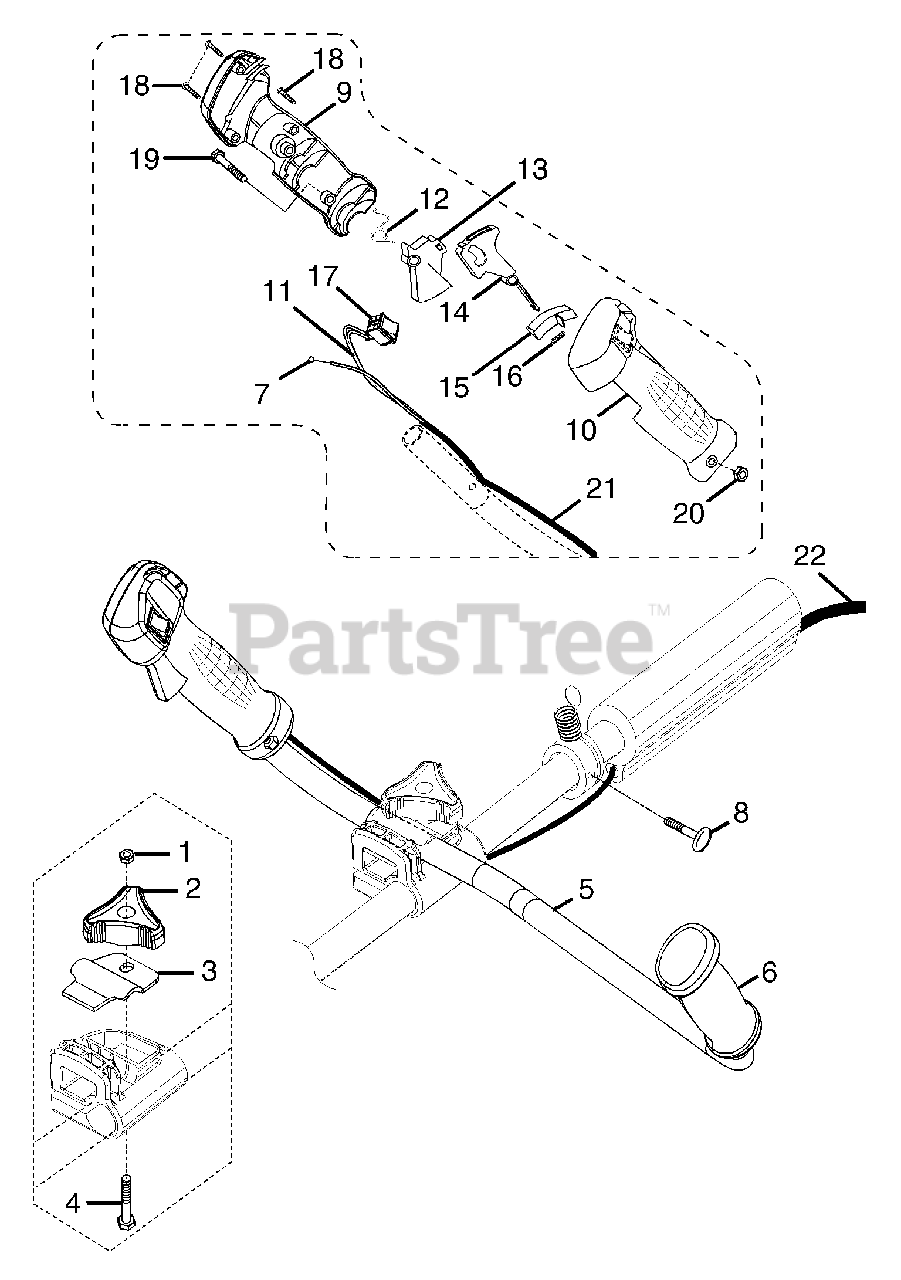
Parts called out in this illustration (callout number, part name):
2	PLASTIC KNOB
3	HANDLE BAR CLAMP
5	HANDLEBAR
6	ASSIST GRIP L/H
7	THROTTLE CABLE
8	THUMB SCREW
9	R/H HANDLE OVERMOLD
10	L/H HANDLE OVERMOLD
11	SWITCH LEAD
12	THROTTLE RETURN SPRING
14	THROTTLE INTERLOCK
15	HALF THROTTLE BUTTON
17	SWITCH
18	SCREW, PLASTITE
19	SCREW (TORX TRUSS HD.)
20	LOCK NUT (LOC HX 10-24)
21	SLEEVING
22	SLEEVING WIRE
